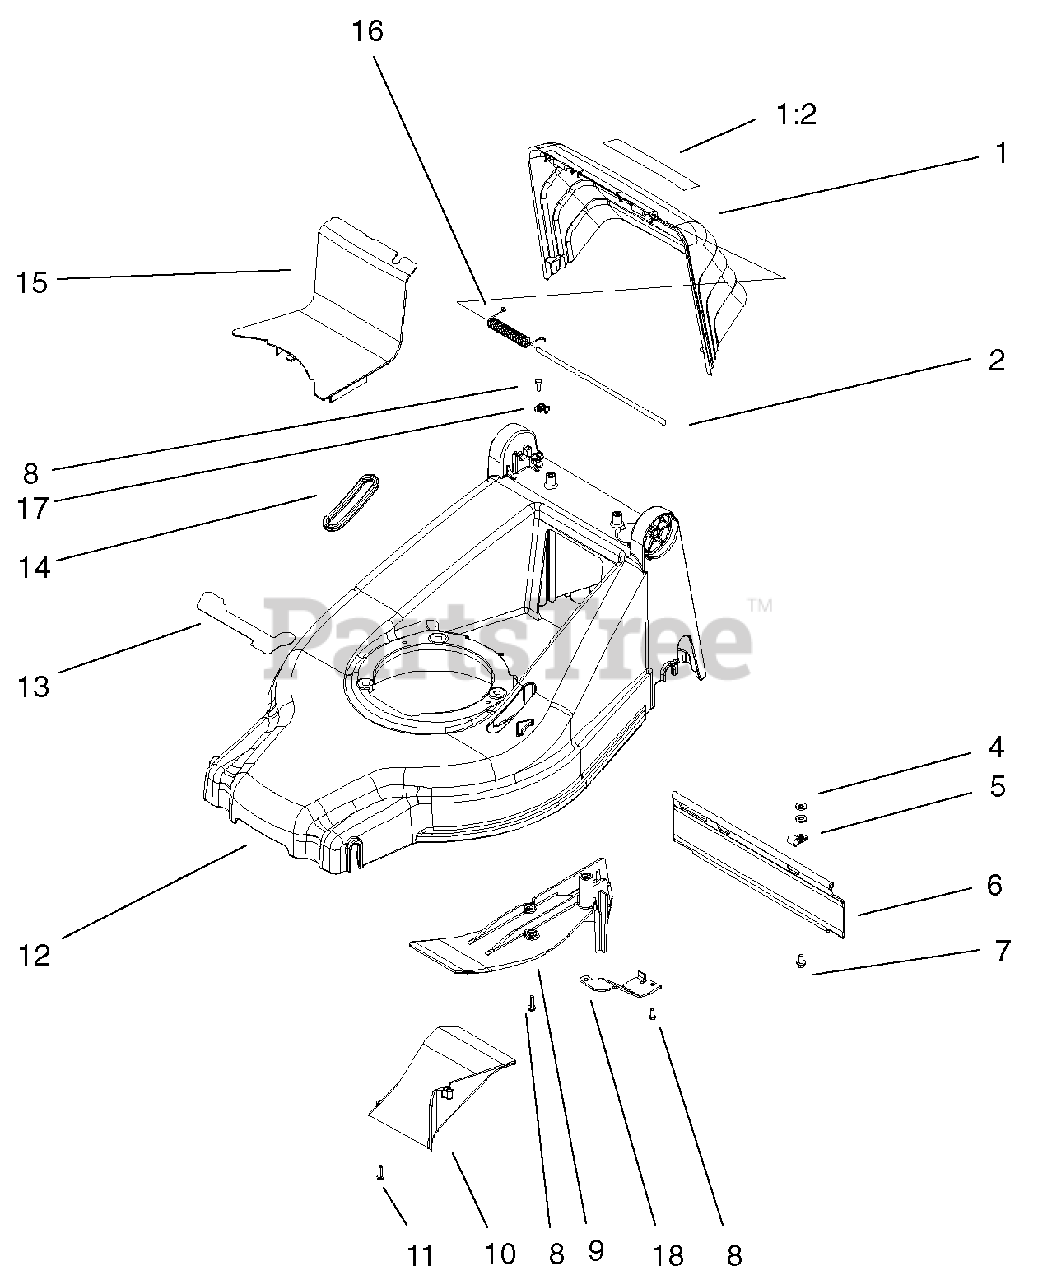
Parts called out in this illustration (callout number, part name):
1	Door-Decal ASM
1:2	Decal-Danger
2	Rod-Pivot, Door
4	Washer-Flat
5	Clamp-Cable
6	Shield-Trailing
7	Screw-Taptite
8	Screw-Taptite
9	Kicker-Cover, Rear
10	Ramp-Discharge
11	Screw-HWH
12	Deck-48cm
13	Decal-Deck
15	Belt Cover
16	Spring-Torsion, Door
18	Bracket-Deck
